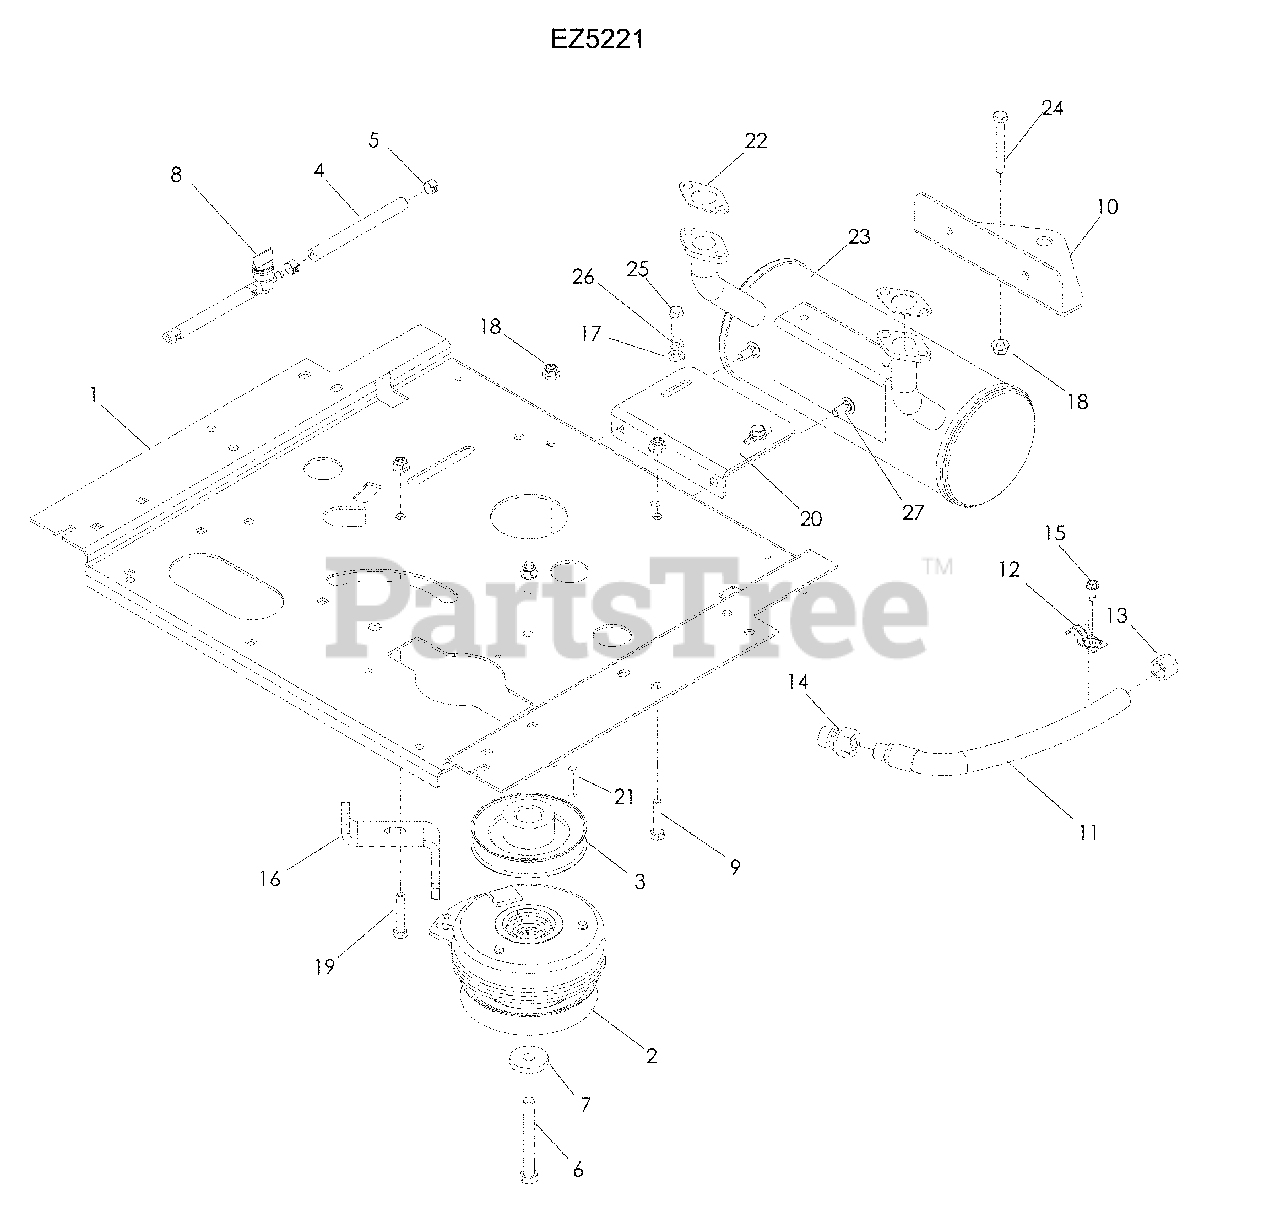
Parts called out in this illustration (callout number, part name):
1	PLATE, ENGINE
2	CLUTCH, 105 FT/LBS
4	FUEL LINE 5"
5	CLAMP, HOSE
6	HCS 7/16-20 x 3½
7	WASHER, CLUTCH
8	VALVE, FUEL
9	HCS 5/16-18 x 1½
11	HOSE, DRAIN
14	ADAPTER, OIL DRAIN
15	SCREW ¼-20 x 5/8 SLF TAP
16	STOP, CLUTCH
17	WASHER 5/16 SAE FLAT
18	NUT 5/16-18 FLANGE NYLOC
19	HCS 5/16-18 x 1¾
20	BRACKET, MUFFLER
21	KEY ¼ SQ x 1¼
22	GASKET, EXHAUST
24	HCS 5/16-18 x 2½
25	HCS 5/16-18 x 1
26	WASHER 5/16 SLW
27	RHSNB 5/16-18 x ¾
